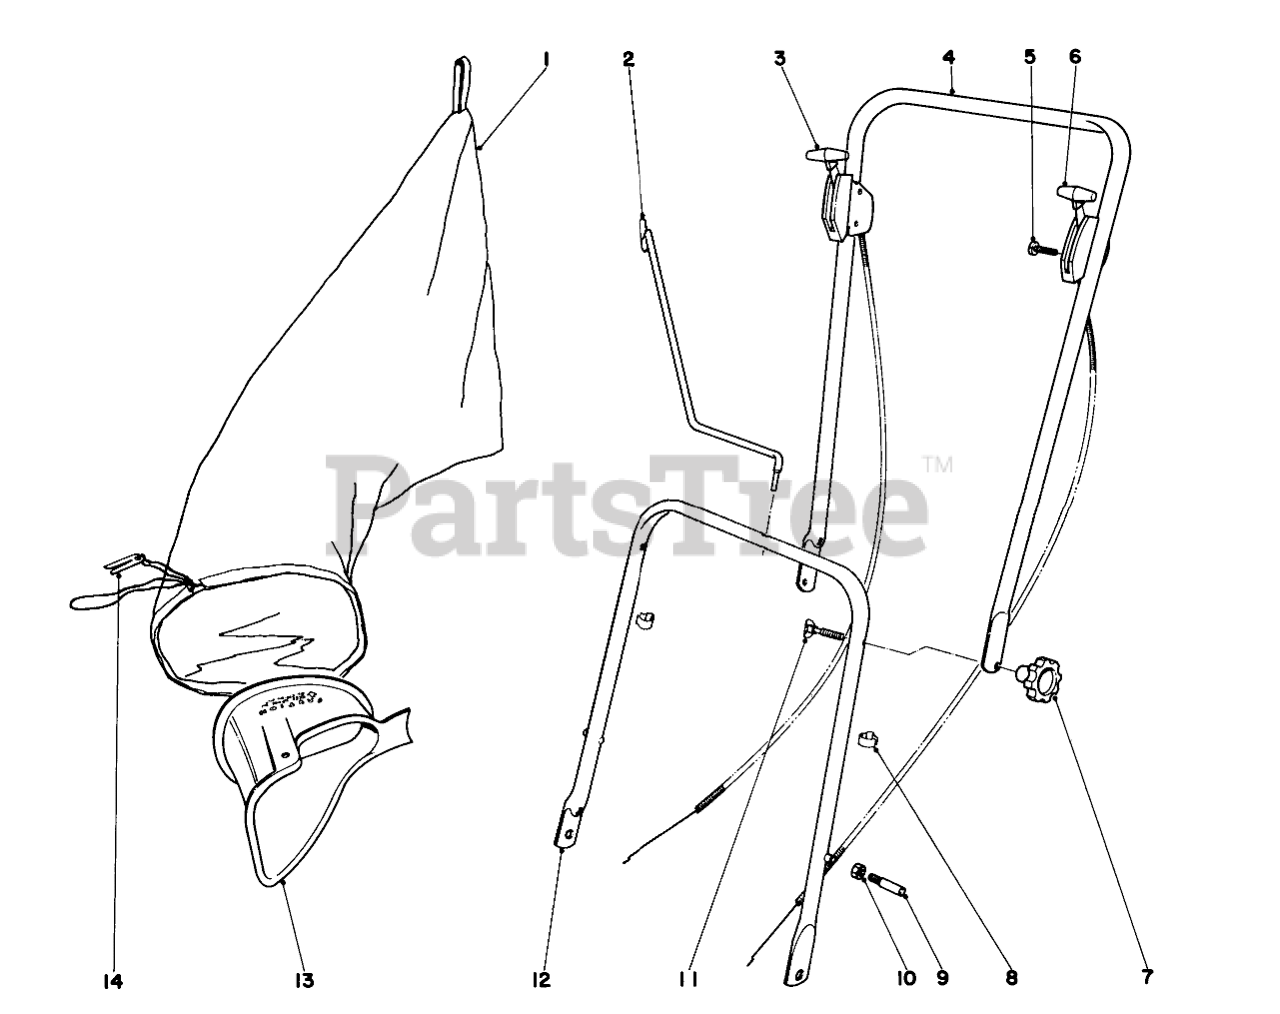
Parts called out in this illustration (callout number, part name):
1	Grass Bag Kit
2	GRASS BAG HANGER
3	Control-Throttle
4	Handle-Upper
5	10-24 X 1 PAN HD SCR
6	Traction Control
7	Handle Release Knob
8	CONTROL WIRE CLIP
9	Handle Pin
10	Nut
11	1-1/4 LG HANDLE SCREW
12	LWR HANDLE STAKED ASM
13	Bag Attachment
14	BAG CORD FASTENER
